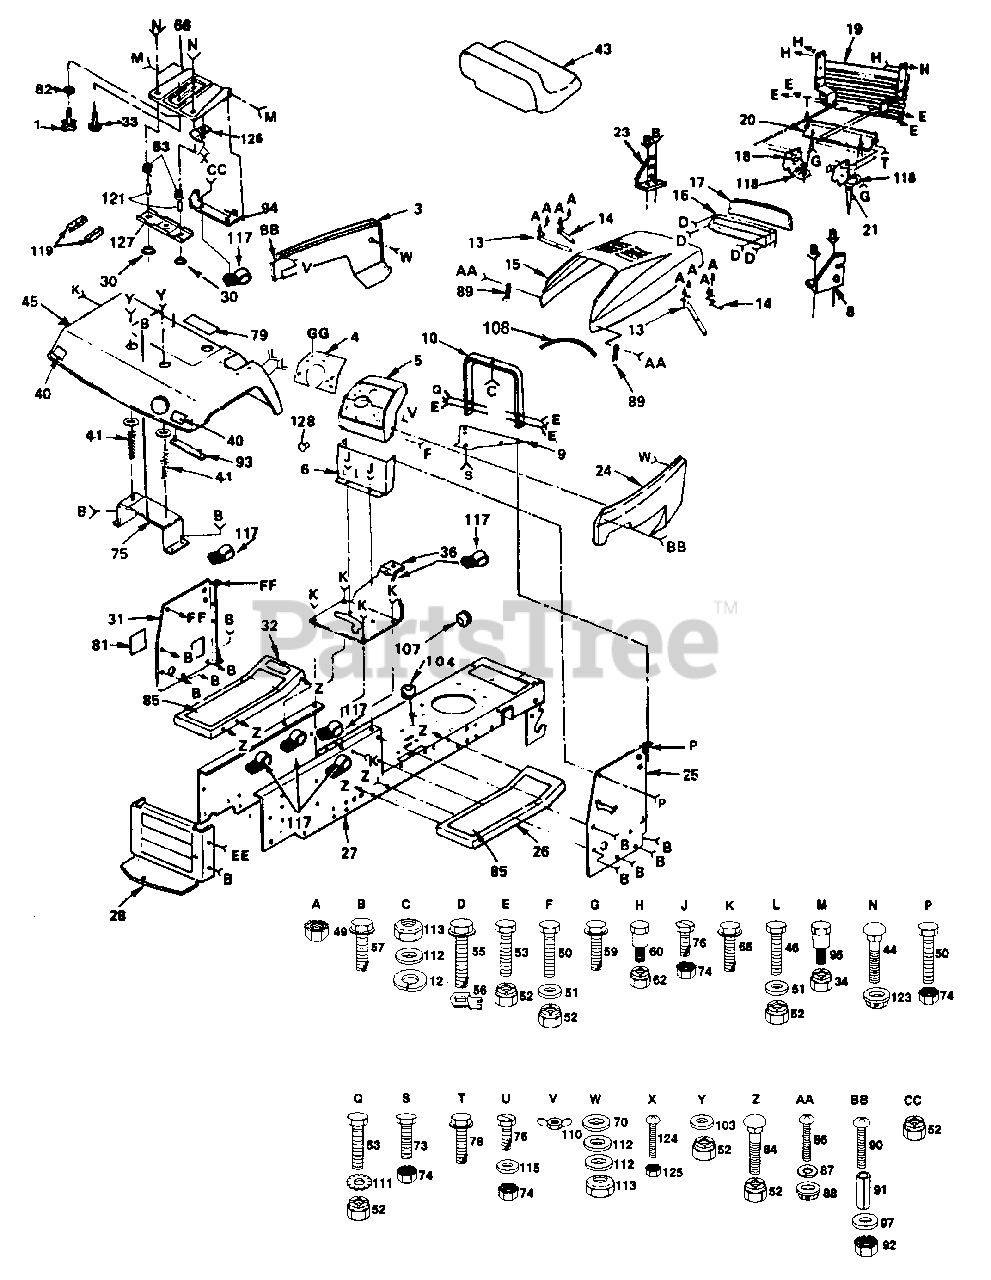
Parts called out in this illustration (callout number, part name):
1	Adjustment Knob (AYP part number)
3	Panel, Side, L.H. (AYP part number)
4	Dash, Plate (AYP part number)
5	Dashboard (AYP part number)
6	Dash Assembly, Lower (AYP part number)
8	Bracket Assembly, R.H. (AYP part number)
9	Plate, Support, Battery (AYP part number)
10	Support, Assembly, Dash (AYP part number)
12	Washer, Lock Heavy Helical 1/4 (AYP part number)
13	Strap, Assembly, Hinge, Rear (AYP part number)
14	Strap, Assembly, Hinge, Front (AYP part number)
15	Hood (AYP part number)
16	Bezel, Assembly
17	Lens (AYP part number)
18	Support, Grill, L.H. (AYP part number)
19	Grill, Assembly (AYP part number)
20	Strap, Grill (AYP part number)
21	Support, Grill, R.H. (AYP part number)
23	Bracket Assembly, L.H. (AYP part number)
24	Panel, Side, R.H. (AYP part number)
25	Panel, Dash, R.H. (AYP part number)
26	Footrest, R.H. (AYP part number)
27	Chassis (AYP part number)
28	Drawbar (AYP part number)
30	Bushing, Snap (AYP part number)
31	Panel, Dash, L.H. (AYP part number)
32	Footrest, L.H. (AYP part number)
33	Bolt, Shoulder 5/16-18 x.62 (AYP part number)
34	Nut, Crownlock 5/16-18
35	Cap, Spring (AYP part number)
36	Saddle (AYP part number)
40	Reflector, Taillight (AYP part number)
41	Spring, Compression (AYP part number)
43	Seat (AYP part number)
44	Bolt, Carriage 1/4-20 x 1-3/8
45	Fender (AYP part number)
46	Bolt, Fin, Hex 3/8-16 x 3/4 (AYP part number)
49	Nut, Hex Keps 1/4-20 (AYP part number)
50	Bolt, Hex 3/8-16 x 1-1/4 (AYP part number)
51	Washer 13/32 x 13/16 x 12 Gauge (AYP part number)
52	Nut, Crownlock 3/8-16
53	Bolt, Hex 3/8-16 x 1 (AYP part number)
55	Screw, Hex Washer Head Tapping #10-16 x 5/8 (AYP part number)
56	"J" Fastener (AYP part number)
57	Screw, Hex Washer Head, Threaded, Rolling 3/8-16 x 3/4 Type TT (AYP part number)
59	Screw, Hex Washer Head, Threaded, Rolling 5/16-18 x 3/4 Type TT
60	Bolt, Shoulder 1/4-20 (AYP part number)
62	Nut, Crownlock 1/4-20 (AYP part number)
63	Spring, Compression (AYP part number)
65	Screw, Hex Washer Head, Thread Forming 3/8- 16 x 1/2 Type TT (AYP part number)
66	Pan, Seat (AYP part number)
70	Washer 9/32 x 5/8 x 16 (AYP part number)
73	Bolt, Hex 5/16-18 x 3/4 (AYP part number)
74	Nut, Keps 5/16-18 (AYP part number)
75	Bracket Assembly, Fender (AYP part number)
76	Screw, Machine 5/16-18 x 3/4 (AYP part number)
78	Screw, Hex Washer Head 1/4-20 x 3/4 (AYP part number)
81	Cover, Access (AYP part number)
82	Washer 17/32 x 1-3/16 x 12 Gauge (AYP part number)
84	Bolt, Carriage 3/8-16 x 3/4 (AYP part number)
85	Pad, Footrest (AYP part number)
86	Screw, Cross Recess Pan Head, Machine #1 0-24 x 1/2 (AYP part number)
87	Washer, Lock #10 (AYP part number)
88	Nut, Weld (AYP part number)
89	Latch, Hood (AYP part number)
90	Screw, Machine, Cross Recess #10-24 x 1-1/4 (AYP part number)
91	Spacer, Split #10 x 3/4 (AYP part number)
92	Nut, Keps #10-24 (AYP part number)
93	Strap Assembly, Fender (AYP part number)
94	Bracket, Pivot, Seat (AYP part number)
95	Bolt, Shoulder 5/16-18 (AYP part number)
97	Washer 7/32 x 1/2 x 18 Gauge (AYP part number)
103	Washer 13/32 x 1 x 14 Gauge (AYP part number)
104	Grommet (AYP part number)
107	Grommet, Split (AYP part number)
108	Foam, Strip (AYP part number)
110	Wing Nut 1/4-20 (AYP part number)
111	Washer, Lock, External Tooth 3/8 (AYP part number)
112	Washer 9/32 x 3/4 x 16 Gauge (AYP part number)
113	Nut, Hex 1/4-20 (AYP part number)
115	Washer 11/32 x 3/4 x 12 Gauge (AYP part number)
117	Clip, Insulated (AYP part number)
118	Washer 11/32 x 3/4 x 12 Gauge (AYP part number)
119	Foam, Strip (AYP part number)
121	Spacer, Split 0.28 x 0.88 (AYP part number)
123	Locknut, Hex, Large, Flanged 1/4-20 UNC (AYP part number)
124	Screw, Sltd. Pan Head #10-32 x 1/2 (AYP part number)
125	Nut, Keps #10-32 UNC (AYP part number)
126	Clip, Insulated (AYP part number)
127	Bracket, Switch Mount (AYP part number)
128	Plug, Button (AYP part number)
129	Nut, Keps Hex 3/8 - 16 UNC (AYP part number)
